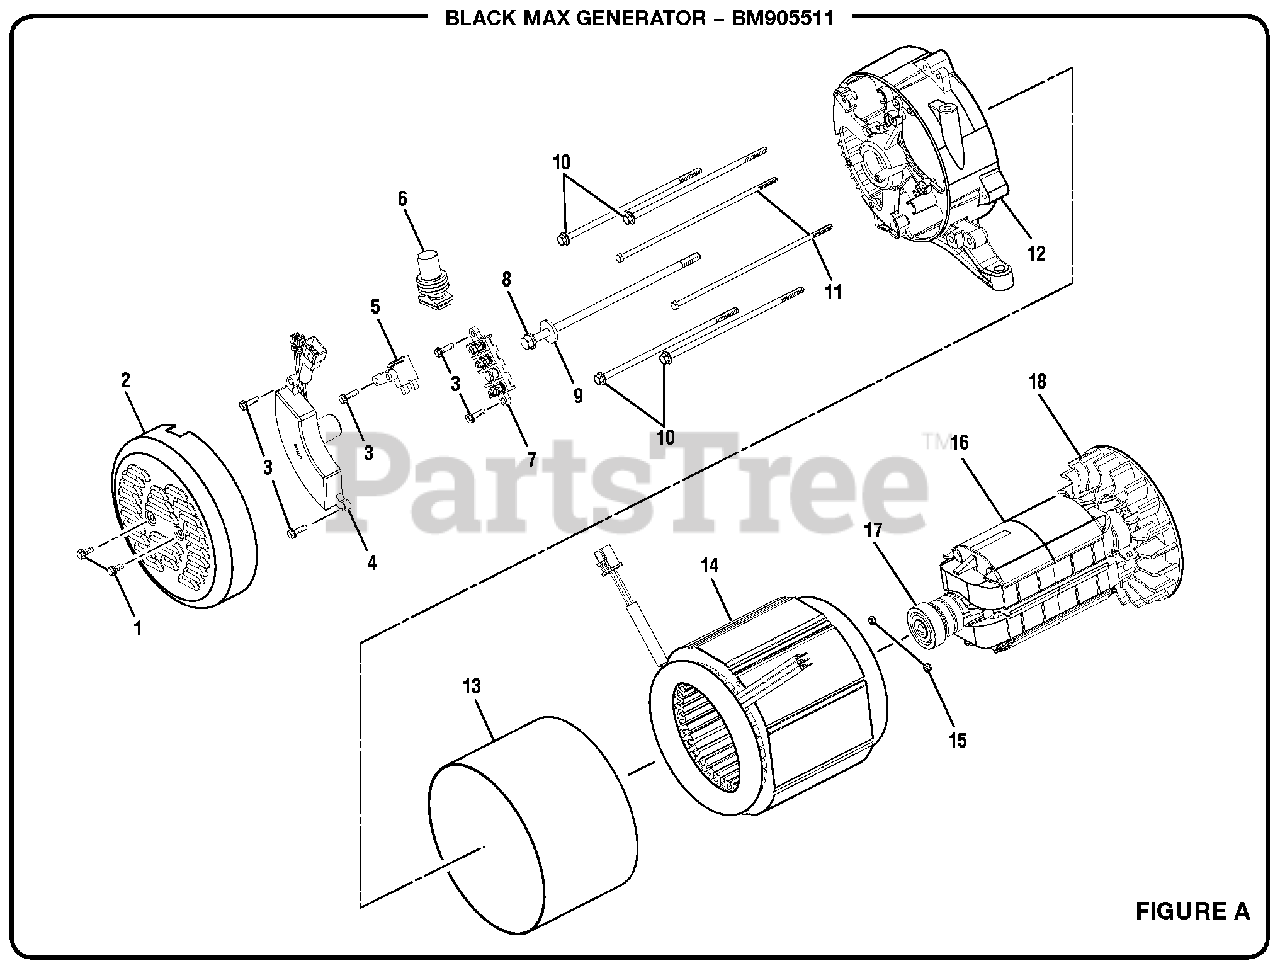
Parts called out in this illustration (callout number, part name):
1	Bolt (M5 x 12 mm, Flange Hex Hd.)
2	Brush Cover
3	Bolt (M5 x 16 mm, Flange Hex Hd.)
4	Automatic Voltage Regulator
5	Brush Assembly Kit
6	Rubber Boot
7	Terminal Block
8	Rotor Bolt (M8 x 222 mm, Flange Hex Hd.)
9	Washer (ID8.4 x OD25.1 x 3t)
10	Stator Bolt (M6 x 180 mm, Flange Hex Hd.)
11	Bolt (M5 x 200 mm, Hex Hd.)
12	Bearing Support
13	Generator Head Cover
14	Stator Assembly
15	Hex Nut (M5)
16	Rotor Assembly
17	Ball Bearing (190 mm)
18	Fan (190 mm)
